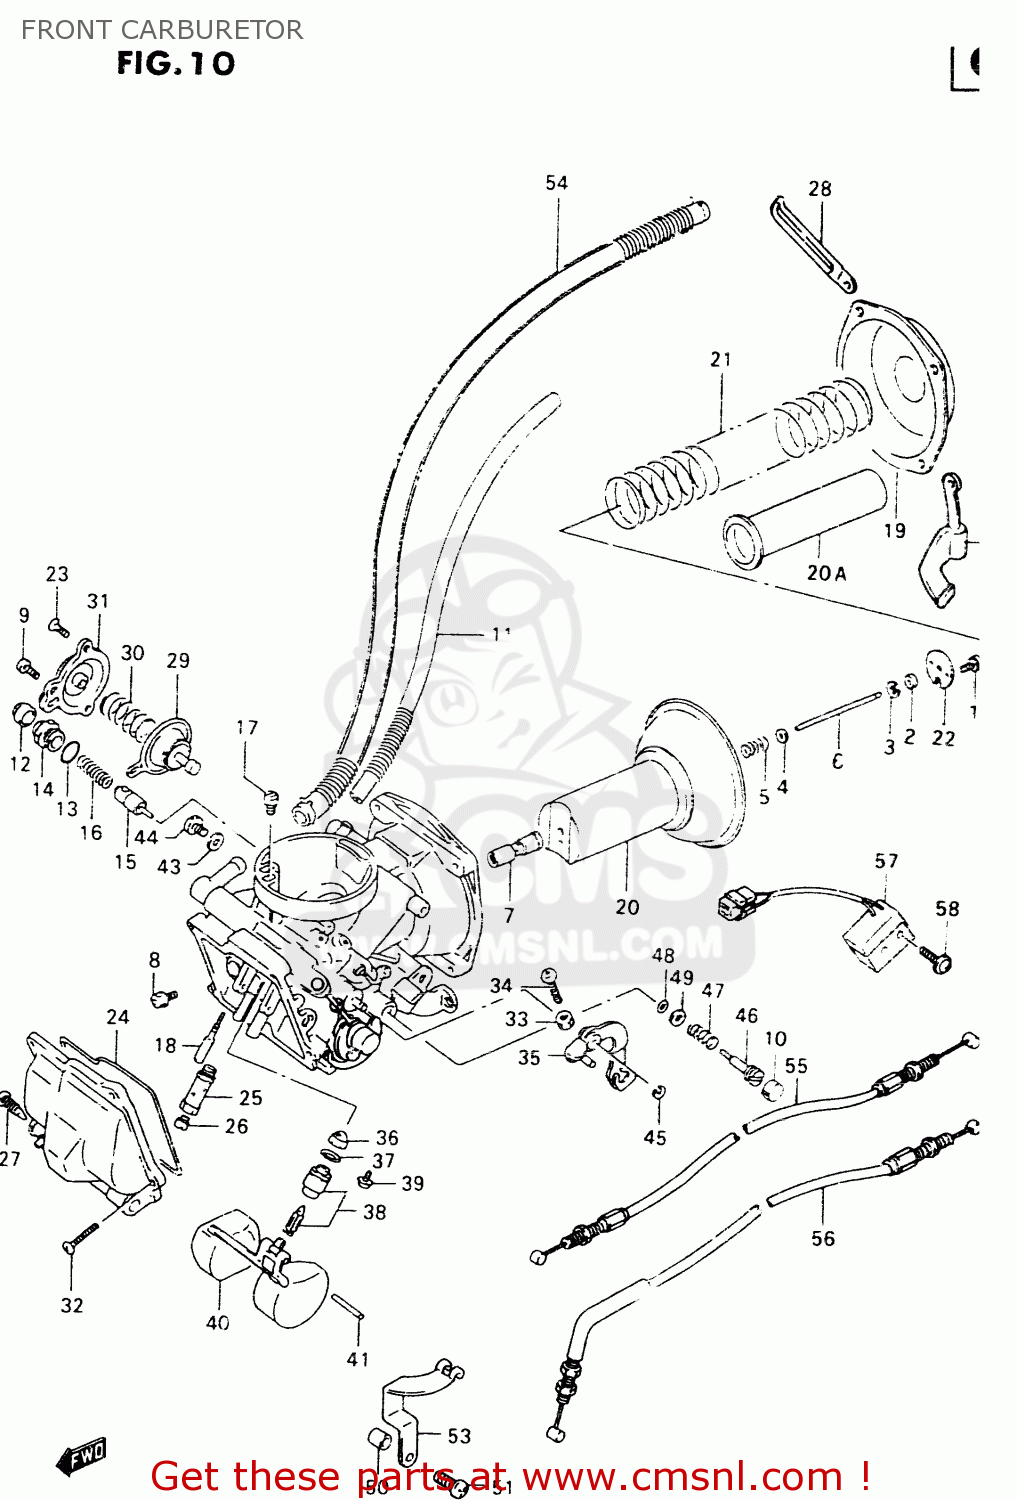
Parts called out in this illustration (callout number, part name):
1	SCREW
2	RING
3	CLIP
4	WASHER
5	SPRING
6	NEEDLE,JET
7	JET,NEEDLE(P-4)
8	SCREW
9	SCREW
10	PLUG
11	HOSE
12	CAP
13	O RING
14	HOLDER,GUIDE
15	PLUNGER,STARTER
16	SPRING
17	JET,AIR(65)
18	JET,PILOT(40)
19	COVER
20	DIAPHRAGM ASSY
20A	RING
21	SPRING,DIAPHRAGM
22	PLATE
23	SCREW,UPPER
24	O RING,FLOAT CHAMBER
25	HOLDER,MAIN JET
26	JET,MAIN (90)
27	SCREW,DRAIN
28	CLAMP(L:65)
29	DIAPHRAGM ASSY
30	SPRING
31	COVER
32	SCREW
33	NUT
34	SCREW
35	LEVER ASSY
36	FILTER
37	O-RING,NEEDLE VALVE
38	VALVE ASSY,NEEDLE
39	SCREW
40	FLOAT
41	PIN,FLOAT
42	SCREW
43	GASKET,DRAIN PLUG (NAS)
44	SCREW(5X6)
45	E RING
46	SCREW,PILOT
47	SPRING
48	O RING,PILOT AIR SCREW
49	WASHER
50	RING
51	SCREW
52	BRACKET
53	BRACKET
54	HOSE ASSY
55	CABLE,IDLE SYNCRO
56	CABLE,THROTTLE RETURN F-R
57	SWITCH,THROTTLE
58	SCREW,THROTTLE SWITCH
